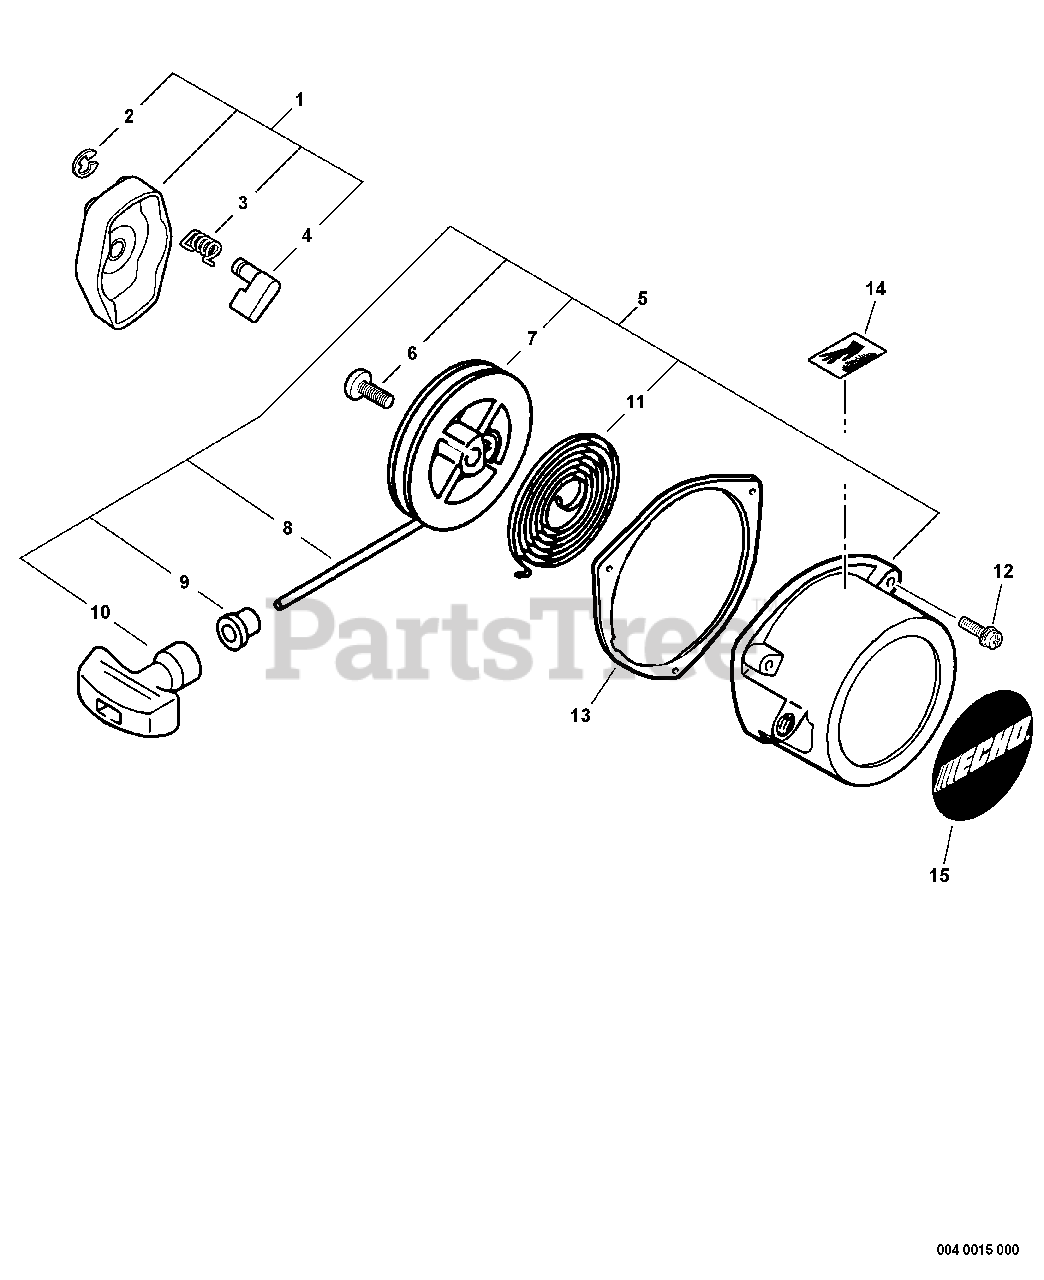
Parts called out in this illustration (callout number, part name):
1	PAWL CATCHER ASSY
2	E-RING 4
3	SPRING, RETURN
4	PAWL, STARTER
5	STARTER ASSY
6	SCREW
7	REEL, ROPE
8	ROPE, STARTER 4.0×880
9	GUIDE, ROPE
10	GRIP, STARTER
11	SPRING, RECOIL
12	SCREW 5×18
13	GASKET, STARTER
14	LABEL, CAUTION - HOT
15	LABEL, ECHO
